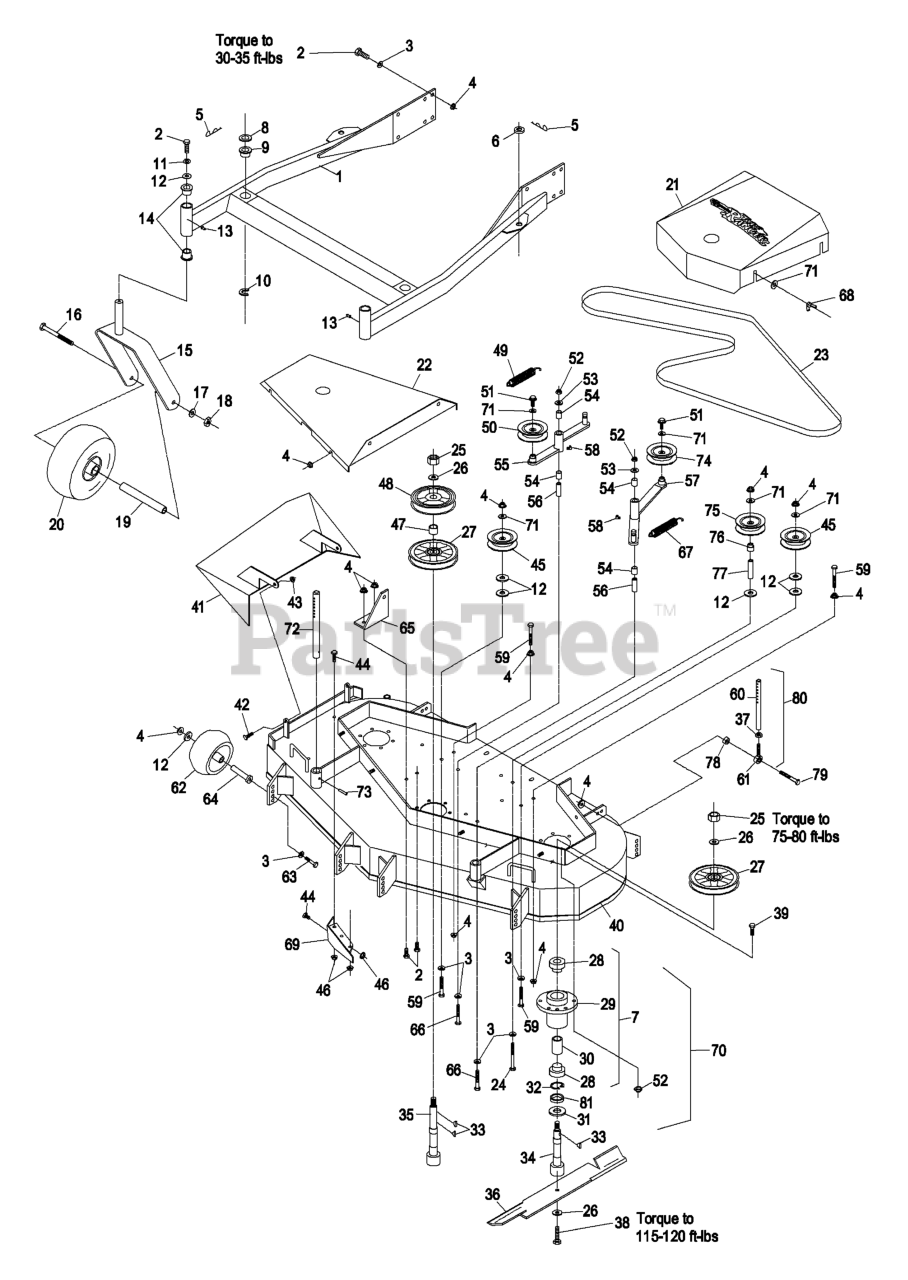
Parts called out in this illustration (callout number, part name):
2	SCREW-HH
3	WASHER-BELLEVILLE
4	NUT-HHF, WHIZ
5	Hairpin, .177
8	SPACER-DECK SUPPORT
9	BUSHING-DECK
10	RING-RETAINING
11	WASHER-LOCK
12	WASHER
13	FITTING-GREASE
14	BEARING-FLANGED
16	SCREW-HH
17	WASHER-LOCK
18	NUT-HH
23	BELT,BLADE DRIVE
24	SCREW-HH
25	NUT-HEX
26	WASHER-SPRING
27	SHEAVE,BLADE DRIVE
28	BEARING
30	SPACER-BEARING
31	GUARD-BEARING, BOTTOM
32	RING-SNAP
33	KEY-WOODRUFF
34	SHAFT,SPINDLE SHORT
37	NUT-HEX
38	SCREW-CAP
39	SCREW-HH
41	WLD,CHUTE DISCHARGE
42	SCREW-HH
43	NUT-LOCK, NI
44	SCREW-HH
45	IDLER,PULLEY
47	SPACER-TUBE
48	SHEAVE,MOWER DRIVE
49	SPRING-EXTENSION
50	IDLER,PULLEY
51	SCREW-HHF
52	NUT-LOCK, NI
53	WASHER-FLAT
54	SLEEVE-BEARING
55	ASM,IDLER ARM
56	BUSHING-PIVOT, IDLER
57	ASM,IDLER ARM
58	FITTING-GREASE, 90 DEG
59	SCREW-HH
60	LINK,SUPPORT
61	BALLJOINT
62	ROLLER-SCALP, ANTI
63	SCREW-HH
64	BUSHING-ROLLER
65	BRACKET,SPRING ANCHOR
66	SCREW-HH
67	SPRING-EXTENSION
68	NUT-WING
69	WLD,BAFFLE DISCHARGE
70	CUTTER HOUSING ASSY,CEN
71	WASHER-FLAT
72	ROD,DECK SUPPORT
74	PULLEY-IDLER
75	PULLEY-IDLER
76	BUSHING,IDLER
77	SPACER-FENDER
79	SCREW-HH
81	SPACER-PULLEY/BEARING
